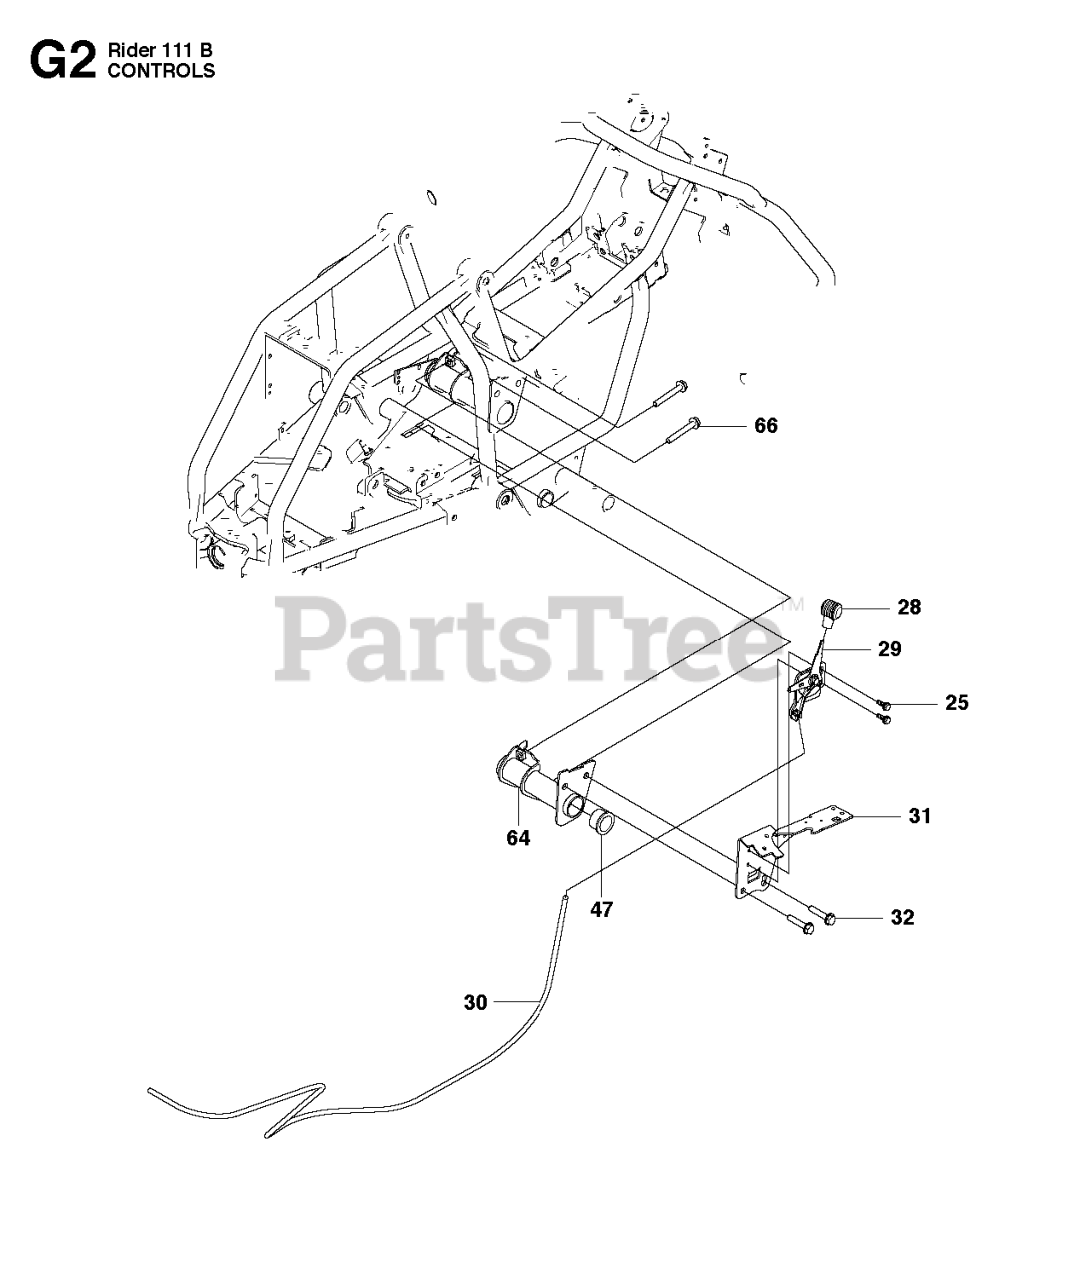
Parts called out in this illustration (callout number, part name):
29	THROTTLE CONTROL
47	ROLLER
66	SCREW
